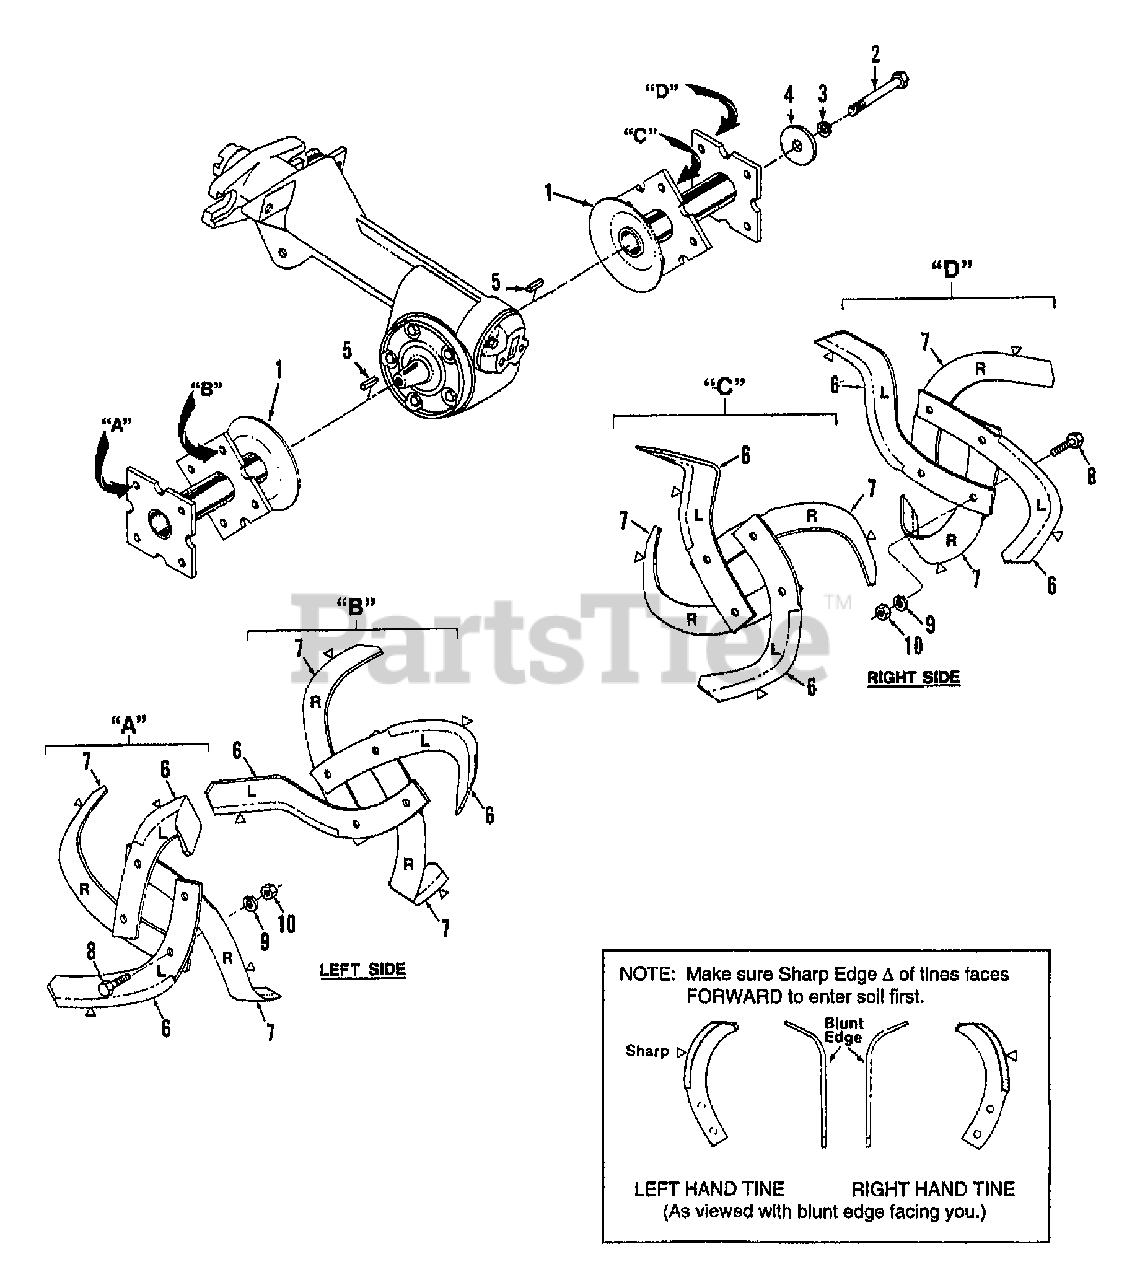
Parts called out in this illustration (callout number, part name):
1	HOLDER-TINE BLACK
2	SCR-HH 1/2-20X4.75 GR5
3	WASHER-LK .5
4	WASHER-1.5X.531X.187
5	KEY-.188 SQX1.0
6	TINE-HARD FACED LT
7	TINE-HARD FACED RT
8	SCR-HH 3/8-16X1.0 G5 ZP
9	WASHER-LK .375 @ DEPL
10	NUT-HEX 3/8-16 ZP
